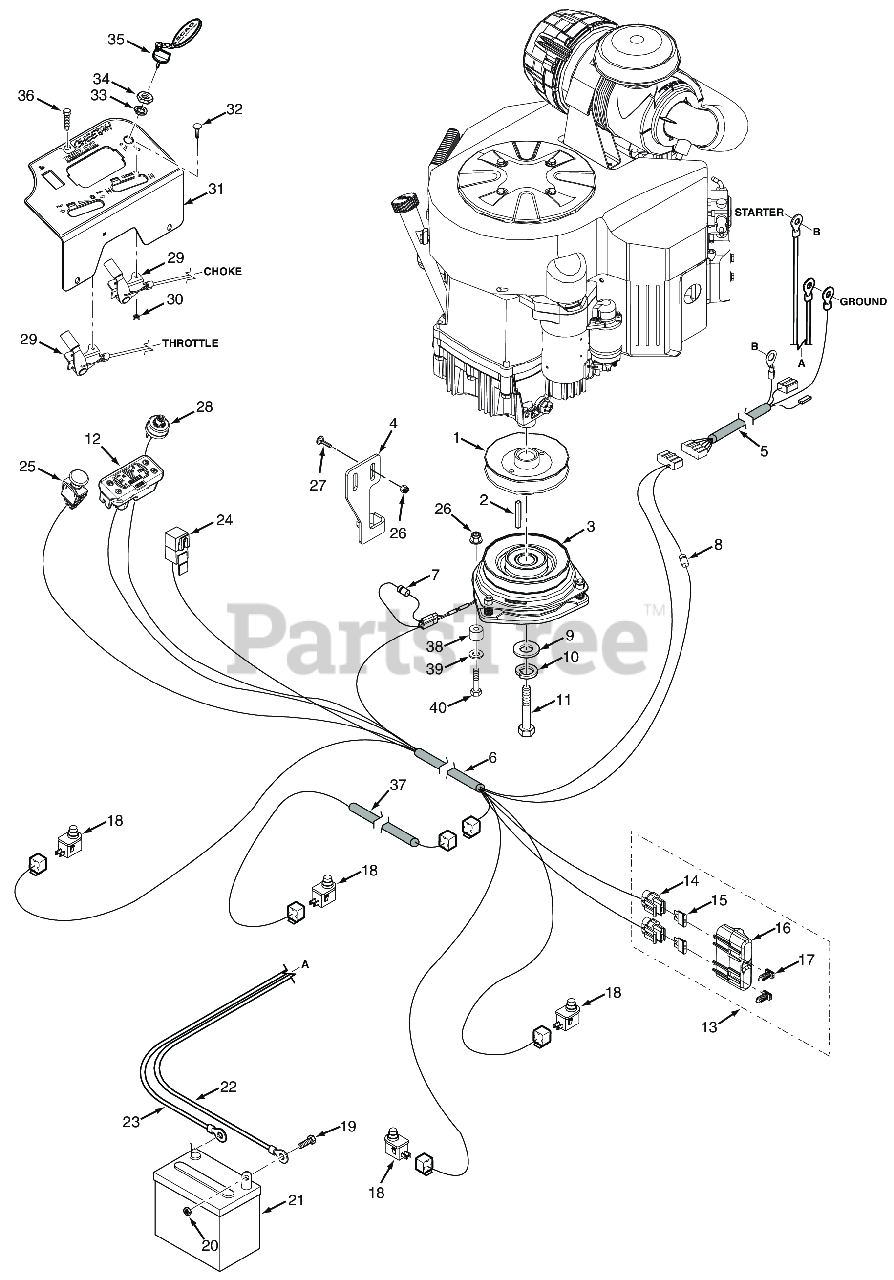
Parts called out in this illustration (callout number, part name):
1	Pulley, 5.80" Dia. - 1.125 Bore
2	Key, 1/4 x 1/4 x 3-1/4�
3	Electric Clutch w/Tag - GT-3.5 (FX850)
3	Electric Clutch w/Tag - GT-5 (ECV860, ECV940)
4	Bracket, Anti-Rotation
5	Wire Harness Adapter, Kawasaki - 22FX & 23FX
6	Wire Harness, SCZ
7	Diode, 600V 6 Amp
8	Decal, Forward Speed Selector
9	Flatwasher, 7/16-.469 x 1.75 x .25 (48, 52)
10	Lockwasher, 7/16� Spring
11	Bolt, Hex Head 7/16-20 x 2-1/4" w/Patch (Kawasaki)
12	Tiger Eye, Cluster Gauge
13	Double Fuse Assy.
14	Fuse Holder Assembly
15	FUSE, 20 AMP BLADE TYPE AUTOMOTIVE
16	Cover, Sealed Double
17	Clip, Fuse Holder
18	Switch, Interlock, Normally Open
19	Bolt, Hex Head 1/4-20 x .5" Battery, (Not Available Through Scag)
20	Nut, 1/4 - 20 Hex
21	Battery
22	Battery Cable, 27" Black (35BV & 37BV-EFI) - Briggs & Stratton
23	Battery Cable, 25" Red (Kawasaki)
24	Relay, 12V 40 AMP Standard
25	Switch, PTO - 10 Amp
26	Nut, Flange Head Elastic Stop 5/16-18
27	Bolt, Carriage 5/16-18x1" (large frame units only)
28	KEY SWITCH(INCLUDES MOUNTING HARDWARE)
29	Control Cable (Kawasaki FX921 Throttle & Choke Cable)
29	Control Cable, Throttle (35BV)
30	Nut, Elastic Stop #10-24
31	Instrument Panel w/Decal
32	Bolt, Carriage #10-24 x 1/2"
33	LOCK WASHER, 5/8" INTERNAL TOOTH
34	Nut, 5/8-32 Special
35	Key, Assembly w/Fob
36	CAP SCREW, 1/4-20 X 1/2" SERRATED FLANGE HEX
37	Wire Harness, Operator Platform -SCZ
38	Bushing, UHMW
39	Flatwasher, 5/16-.375 x .875 x .083 (35BV & 37BV-EFI)
40	Bolt, Hex Head 5/16-18 x 1-1/2" (Right Front Engine Mounting, Briggs and Kohler Only)
